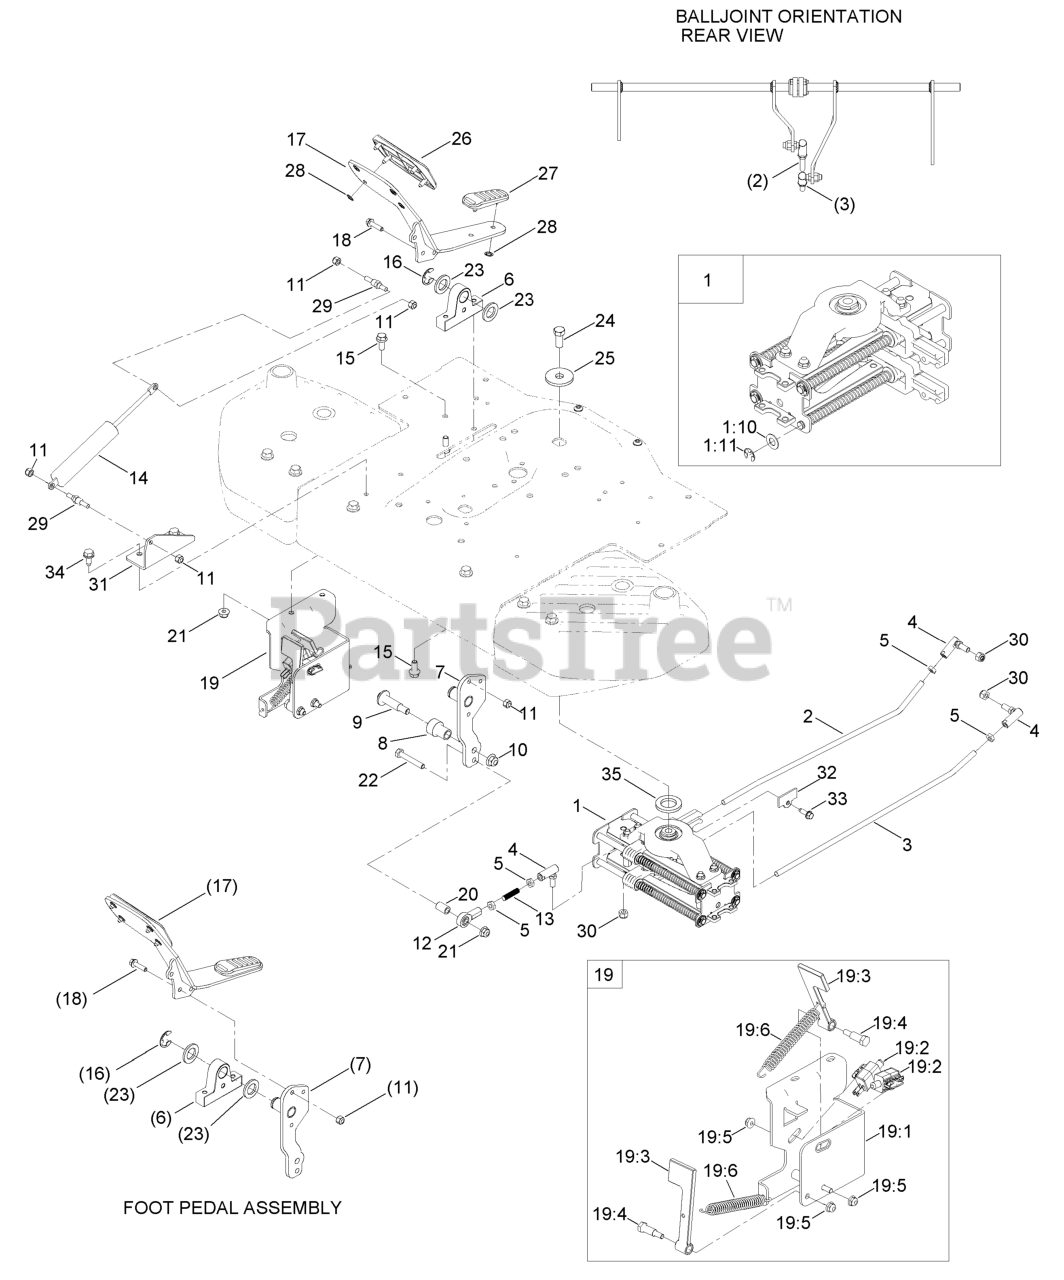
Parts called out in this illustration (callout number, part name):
1	SPEED CONTROL ASM
2	ROD-HYDRO, RH
3	ROD-HYDRO, LH
4	BALLJOINT-RH (W/GROMMET)
5	NUT-JAM
6	MOUNT-PEDAL PIVOT
7	PIVOT LEVER ASM
10	NUT-HF, NI
11	NUT-LOCK, NI
12	BALLJOINT-RH
13	ROD-THREADED
14	DAMPER-NON CAVITATING
15	SCREW-HHF
17	PEDAL-TRACTION
18	SCREW-HHF
19	NEUTRAL RETURN ASM
21	NUT-HF, NI
22	SCREW-HH
24	SCREW-HH
25	WASHER-THRUST
26	PAD-TOE, HYDRO PEDAL
27	PAD-HEEL, HYDRO PEDAL
28	NUT-PUSH
29	STUD-DAMPER
30	NUT-LOCK
31	BRACKET-DAMPER
32	COVER-END ROD
33	SCREW-HWH, THREAD ROLL
34	Screw-HWH 5/16-18 X 3/4 Tf
35	SPACER-BEARING
